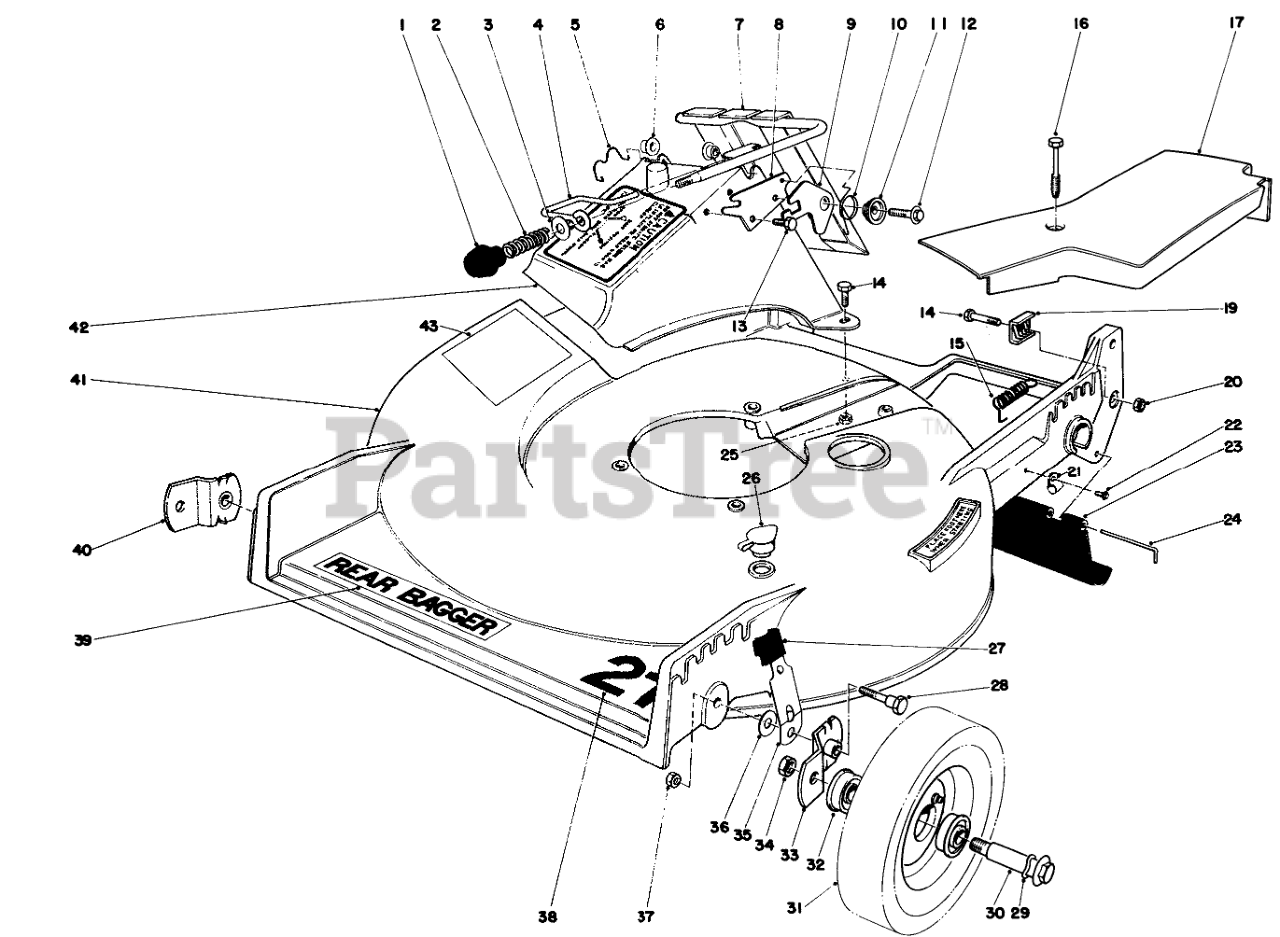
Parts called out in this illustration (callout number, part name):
2	COMPRESSION SPRING
3	WASHER
4	DOOR LATCH
5	DOOR RETAINER
6	BUSHING-NYLON
7	DOOR & HANDLE WA
8	DOOR LATCH PLATE
9	Latch Safety
10	TORSION SPRING
11	Latch Spacer
12	Screw
13	SCREW-HWH
14	SCREW-HH
15	IDLER SPRING
16	SCREW-HHFTF
17	Belt Cover
19	CLAMP-CABLE
20	NUT-JAM
21	CLAMP-NYLON
22	SCREW-HWH
23	SHIELD - TRAILING
24	Rod Shield
25	NUT-LOCK, NI
26	WASHOUT PLUG
27	KNOB-ARM
28	PIVOT SCREW
29	SPRING WASHER
31	Wheel &Tire Assy. (Incl. Ref. #32)
32	BEARING-BALL
33	PIVOT ARM ASM A
34	Nut
35	Spring Arm
36	Washer
37	Nut
38	Decal 21"
39	DECK DECAL
40	PIVOT ARM ASM B
41	Housing
42	DISCHARGE CHUTE B
43	Decal-Caution (French & Dutch)
